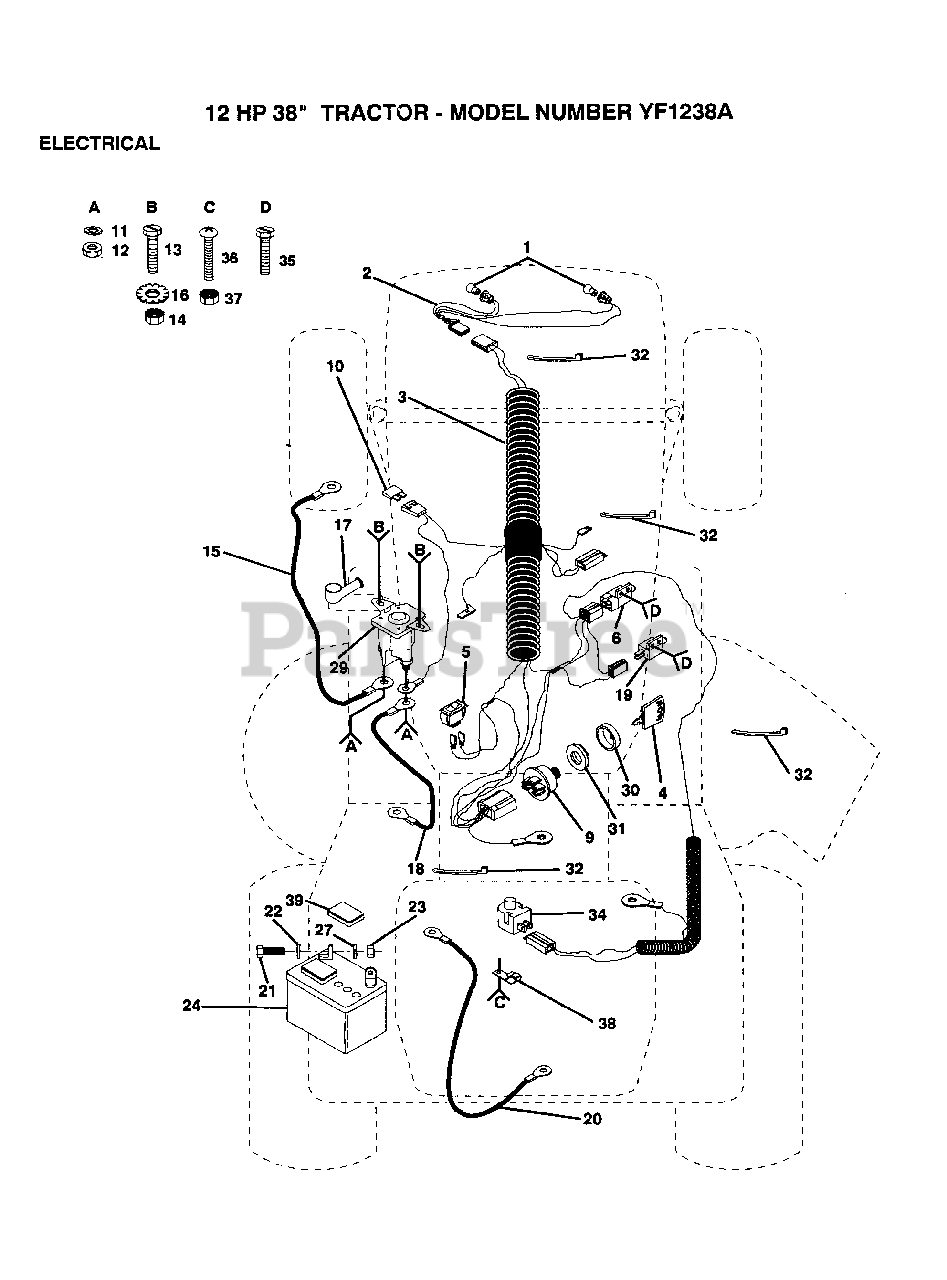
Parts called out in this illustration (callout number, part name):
2	HARNESS T
3	IGN HARNESS
4	KEY
5	SWITCH LT
6	SWITCH INTERLOCKT
10	FUSE HYT
12	NUT
13	BOLT
14	NUT
15	"CABLE T, BATTERY"
19	SWITCH-INTER. GT
20	CABLE T
21	BOLT LT
22	WASHER
27	LOCKWASHER
31	NUT IGNITION
32	WIRE TIE
34	SWITCH SEAT
35	SCREW
37	"NUT,KEPS"
39	"CAP,BATTERY "
